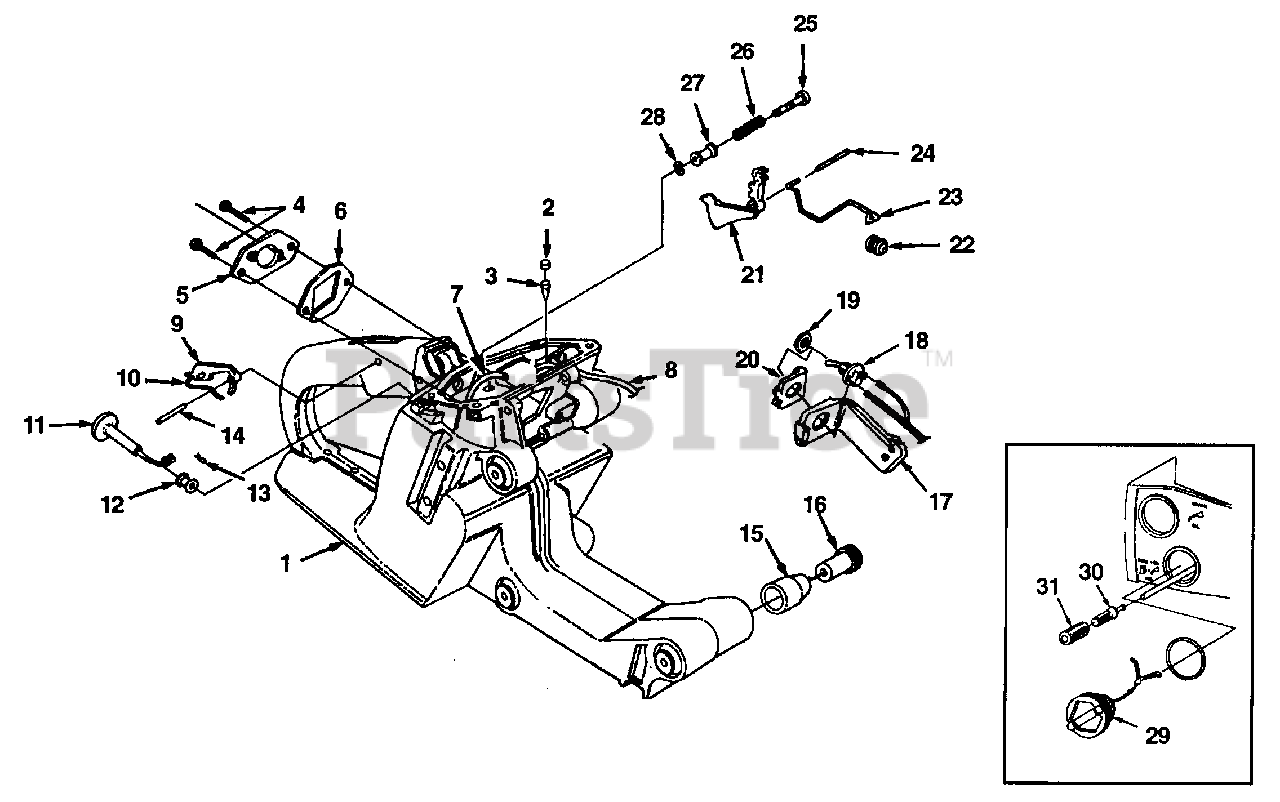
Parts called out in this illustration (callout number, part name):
1	HOUSING - Engine
2	TANK VENT FILTER
3	VALVE - Duck Bill
4	SCREW - Torx Truss (10-24 X 1/2")
5	ADAPTOR - Carburetor
6	GASKET - Carburetor
7	TUBING - Rubber (Fuel Line, 9 1/2")
8	TUBING - Rubber (Pulse Line, 6 1/2")
9	TRIGGER - Lock
10	SPRING - Flat
11	ROD - Choke
12	GROMMET
13	PIN - Cotter
14	PIN - Trigger
15	ISOLATOR - Vibration
16	SLEEVE - Flanged
17	COVER, Switch
18	SWITCH - Toggle
19	NUT - Hex
20	PLATE - Indicating
21	TRIGGER - Throttle
22	BOOT - Throttle Rod
23	ROD - Throttle
24	PIN - Trigger
25	PIN - Throttle Lock
26	SPRING - Compression
27	BUSHING - Flanged
28	RING - Retaining
29	FUEL CAP
30	FUEL FILTER
31	FILTER ELEMENT
